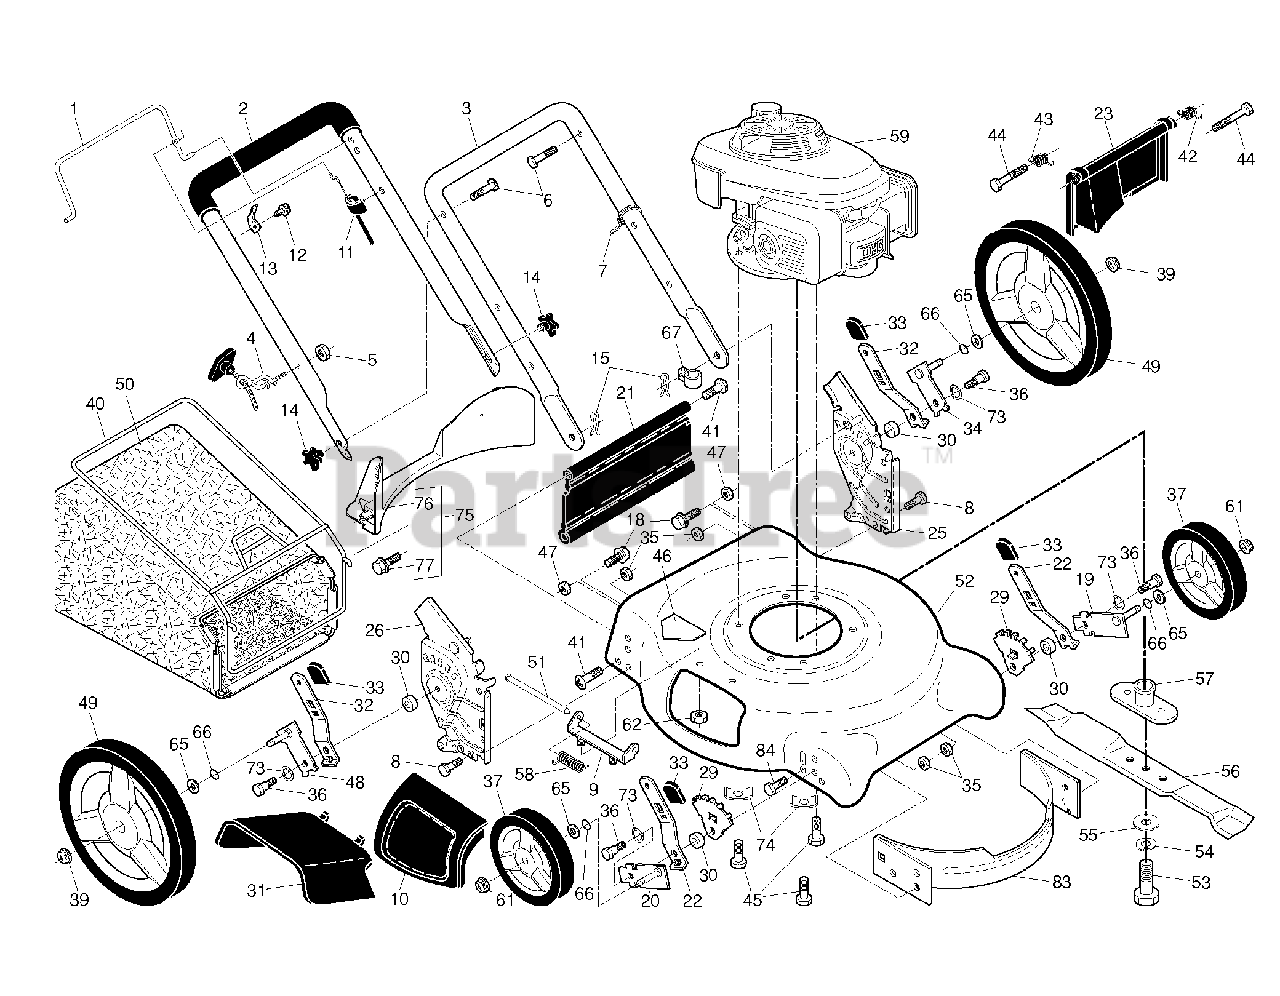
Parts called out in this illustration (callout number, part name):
1	CONTROL BAR
2	HANDLE.UPPER.WITH.GRIP
3	HANDLE.LOWER.D-STRAIT.GREY
4	RB GUIDE.ROPE.STD.BLK.ZIN WSL
5	NUT
6	BOLT, HANDLE 5/16-18X1.75
7	TIE GUIDE
8	BOLT
9	BRACKET.ASM.HOUSING.EZ.MUL
10	RP DOOR.MULCH.21".REAR.PUSH.GR
11	CABLE.MZR.RATO.22"LOW.
13	BRACKET.UPSTOP.RT
14	KNOB.HANDLE.PLASTIC.STAR.BLACK
15	HAIRPIN COTTER
18	SCREW 1/4X20
19	AXLE ARM ASSY FRONT LH
20	AXLE ARM ASSY FRONT RH
21	RP_KIT.SKIRT.21 DOMED.W/LIP
22	SELECTOR SPRING, FRONT
23	REAR DOOR ASSY
25	RP BRACKET.ASM.HND.HW.21.LT.
26	RP BRACKET.ASM.HAND.HW.21.RT.O
29	WHEEL ADJ BRACKET FRONT
30	SPACER.HEIGHT.ADJUSTER(2 2)3 2
31	DEFLECTOR.CLIPPING.21.GREY
32	SPRING.SEL.22.ECON.HI-WHL.RATO
34	AXLE ARM ASSY REAR LH
35	NUT.FLANGE.HEX.5/16X18.BLACK
36	SHOULDER BOLT 5/16-18
37	WHEEL AND TIRE ASSY, REAR
39	NUT.HEX.FLANGE.3/8-16.LOCKNUT
40	FRAME.BAG.21.REAR.DOMED.PUSH
41	SCREW.1/4-20X21/4.HEX.
42	SPRING.LH.22.REAR.DOOR.EZ.EMPT
43	SPRING.RH.22.REAR.DOOR.EZ.
45	BOLT 3/8-16X1-1/8
46	DANGER DECAL
47	NUT.LOCK.5/16-18
48	AXLE ARM ASSY REAR RH
49	WHEEL.12 X 1.75 CFH3SPK.RAD3
50	GBAG.2323247.SILVER
51	ROD.HINGE.COMBI-C
52	HOUSING.21.MC.DOME.ORG.ENG.
53	SCREW, HEX HD 3/8-24 X 1-3/8
54	LOCKWASHER
55	WASHER,HARDEN
56	BLADE.21.PUSH/RWGD/FWGD
57	ADAPTER.BLADE.W/KEY.25MM.CE
58	TORSION SPRING
61	NUT.HEX.FLANGE.3/8-16.LO(3 2)
62	LOCKNUT.NYLOC.1/4-20
66	O-RING..070X.487.NEOPRENE
67	CLIP.CABLE.BLK
73	WASHER.CURVED.CYLINDRICAL
74	WASHER.ENGINE.BZP
75	KIT.BAFFLE.REAR.PLASTIC.21.RD
76	BAFFLE.REAR.PLASTIC.21.RD.ECON
77	SCREW.HX.13X.750
83	BAFFLE.FRONT.21.DOME.US
84	BOLT.5/16HEX.WHS.HD
